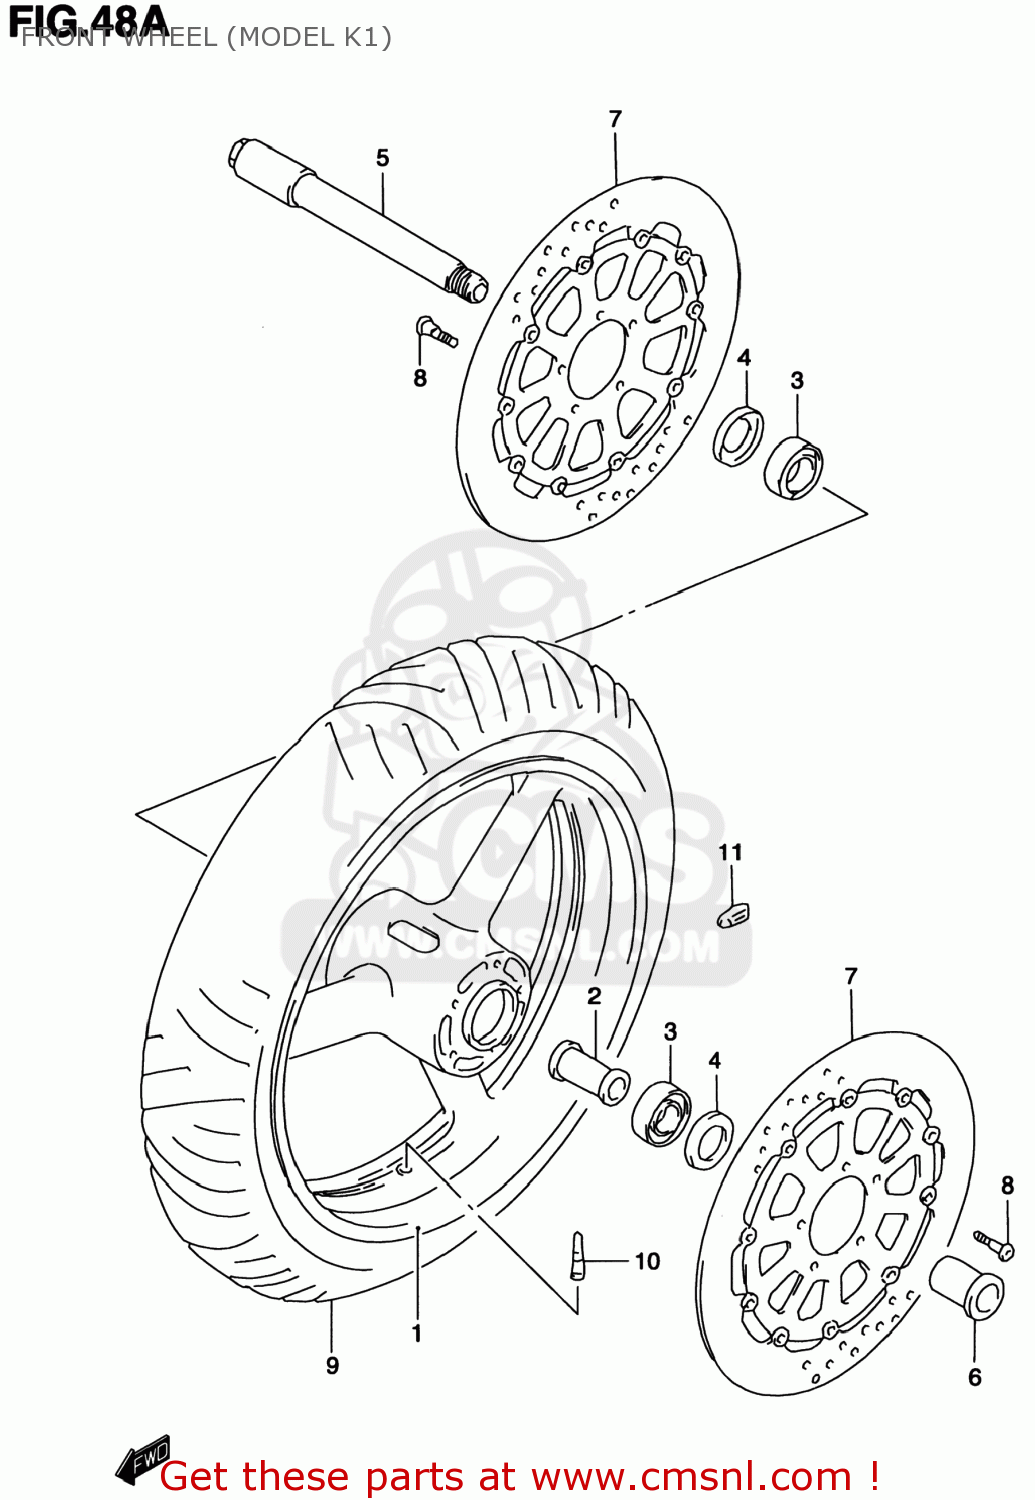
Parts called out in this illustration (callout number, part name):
1	WHEEL,FRONT (17XMT3.50)(
2	SPACER,FR HUB BEARING
3	BEARING(25X52X15)
4	SEAL,OIL(32X52X7)
5	AXLE,FR
6	NUT,FR AXLE
7	DISC,FR BRAKE
8	BOLT 8X33
9	TIRE 120/70 ZR17 (58W),M
10	VALVE ASSY,WHEEL RIM(TR412)
11	BALANCER,WHEEL (10G)
